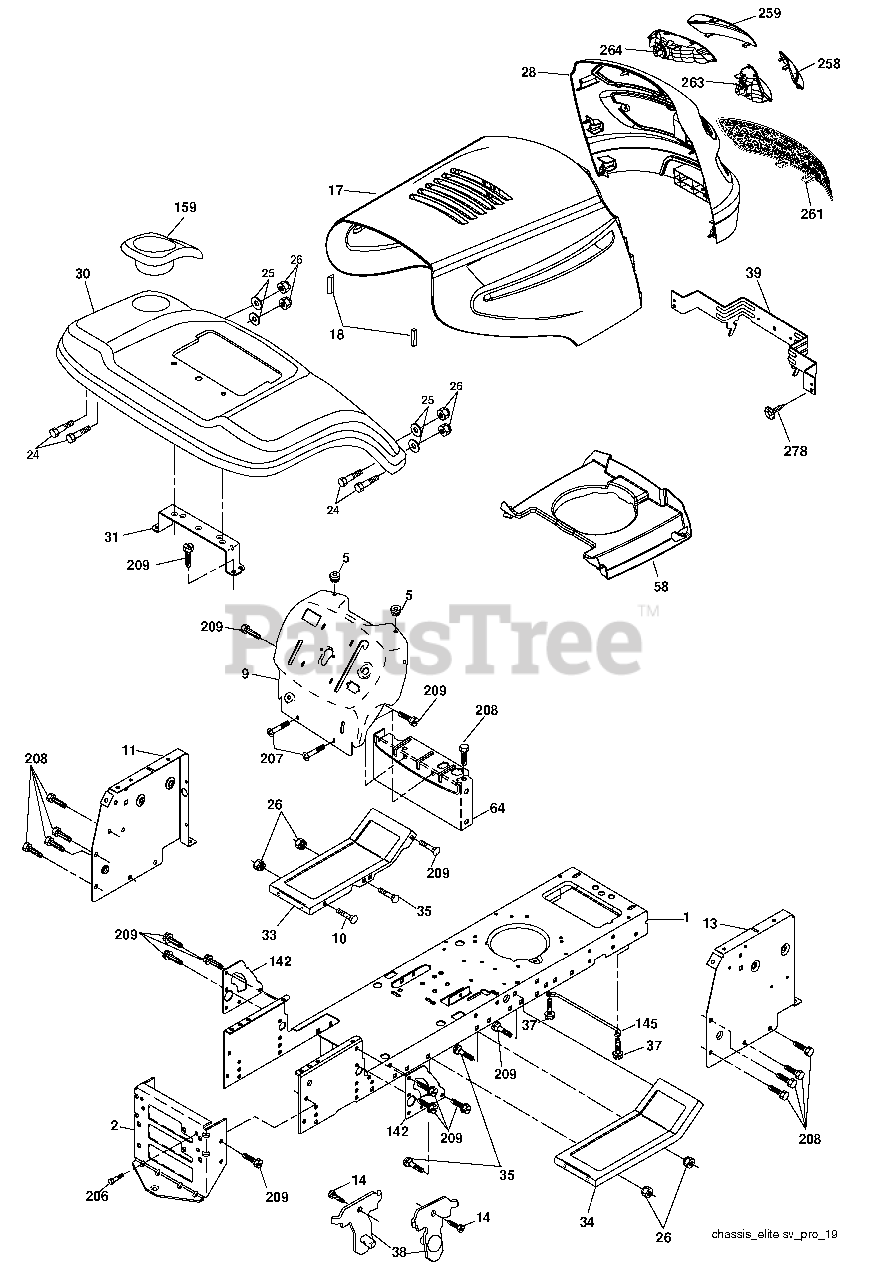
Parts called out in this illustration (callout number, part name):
2	Drawbar
5	Dash
14	Hood
15	Lens Grille LH
18	Grille
25	Lens Grille RH
68	Screw THDROL 5/16-18 x 1/2
99	Rod Bypass Asm
130	Screw 10 x 3/4 Single Lead-Hex
137	Bumper Hood
138	Cupholder
150	Duct Heat Hood
151	Bracket Pivot
152	Shield Browning/Debris
159	Screw Hexwsh Thdrol 3/8-16 x 3/4
162	Screw Hex Wsh Hi-Lo 1/4 x 1/2 UNC
175	Crossmember
176	Screw 10-24 x 5/8 Wshd Qdrx
177	Bushing Steering
181	Bushing Mtg. Fender Crgo.
182	Dash Lower
183	Bolt Fin Hex 5/16-18 x 1-1/4
184	Spacer Fender
189	Screw 5/16-18 x 3/4
194	Nut Lock Hex Flange 5/16-18
196	Console Asm. Deck Lift
197	Rod Pivot Chassis
207	Bezel RH
208	Bezel LH
219	Stud Fastener
222	Screw thd Roll 1/4-20 x 5/8
229	Screw 3/8-16 x 1
230	Bolt Shoulder 5/16-18
230	Plug Cruise/Hook/Phone
